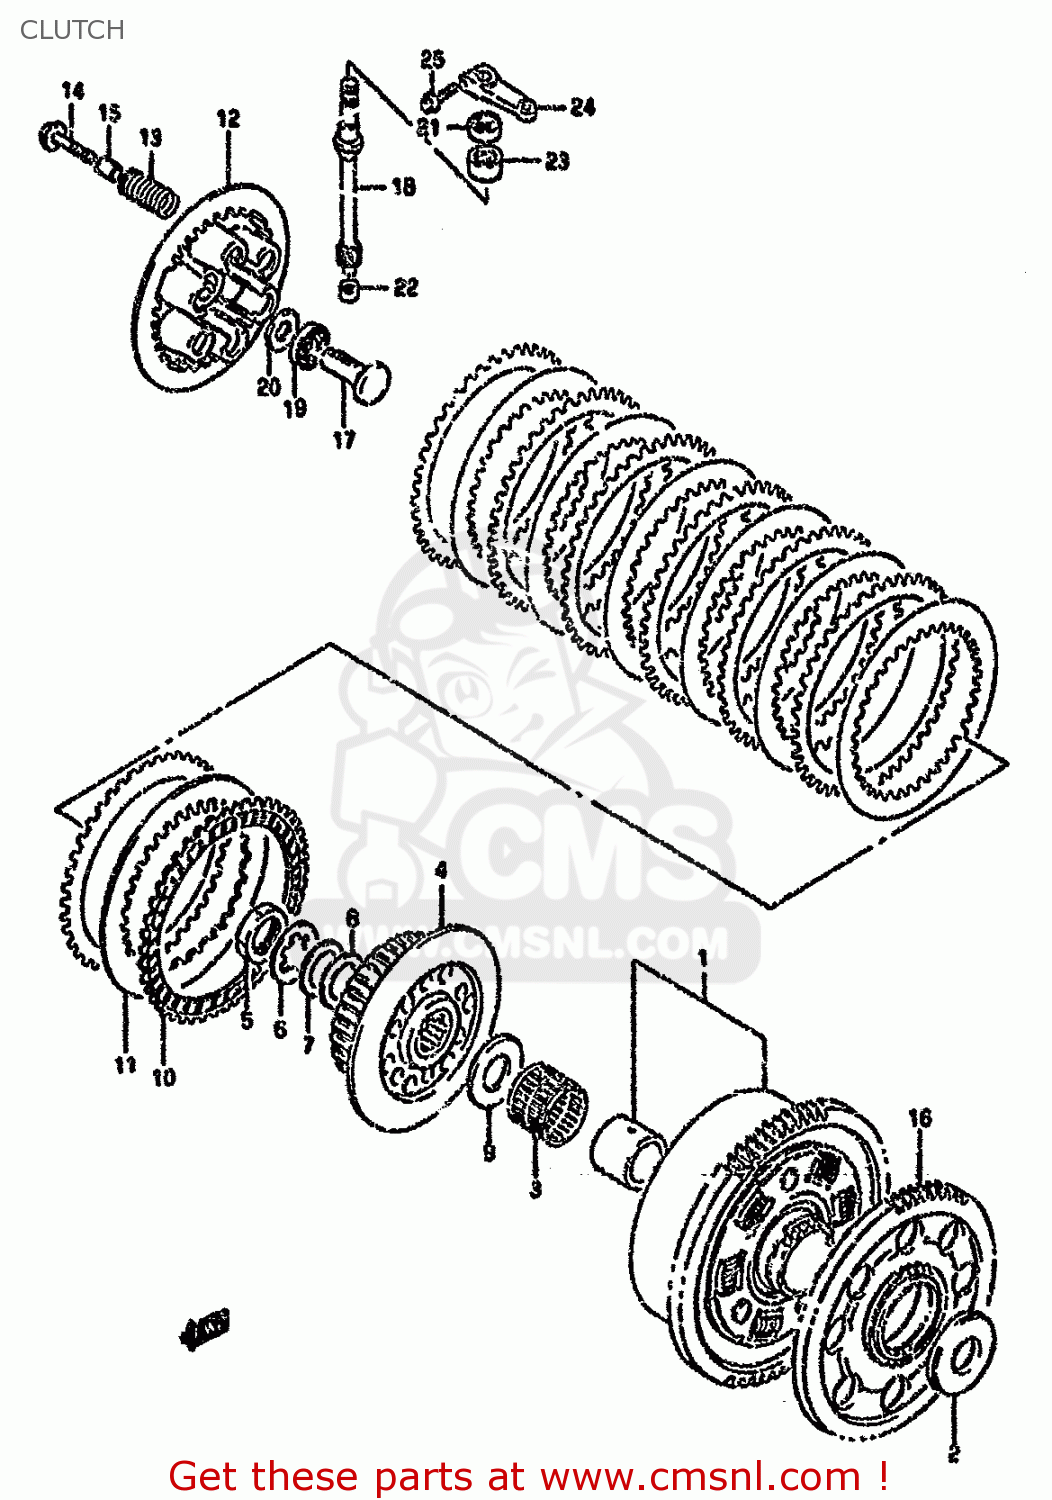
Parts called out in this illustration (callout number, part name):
1	GEAR ASSY,PRI DRIVEN
2	WASHER
3	BEARING(35X40X35.8)
4	HUB,CLUTCH SLEEVE
5	NUT
6	WASHER,LOCK
7	WASHER
8	SHIM
9	WASHER(25X50X2.5)
10	PLATE,CLUTCH DRIVE
11	PLATE,CLUTCH DRIVEN
12	DISC,CLUTCH PRESSURE
13	SPRING
14	BOLT
15	SPACER
16	GEAR,GENERATOR DRIVE
17	RACK,CLUTCH RELEASE
18	PINION,CLUTCH RELEASE
19	BEARING(15X28X2)
20	WASHER
21	OIL SEAL
22	BEARING 10X14X10
23	BEARING(15X22X12)
24	ARM,CLUTCH RELEASE
25	BOLT
